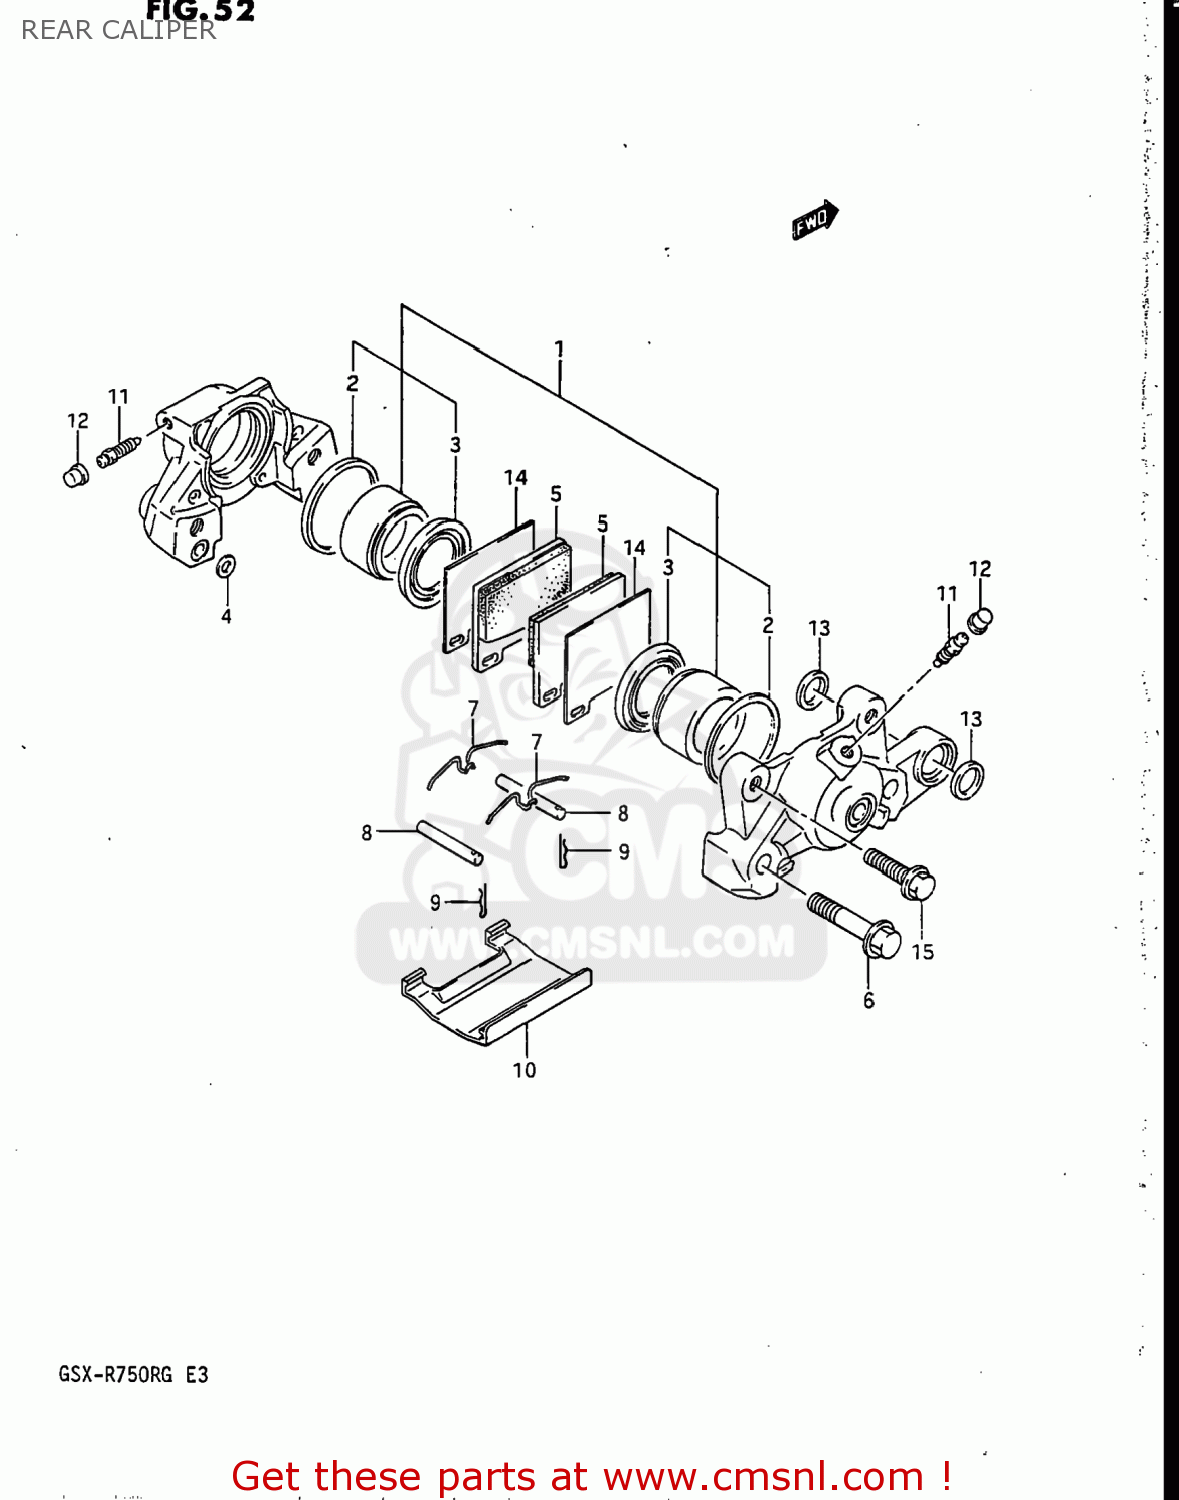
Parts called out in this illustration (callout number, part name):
1	PISTON SET
2	SEAL,PISTON
3	BOOT
4	SEAL,JOINT
5	PAD,BRAKE
6	BOLT,HOUSING
7	SPRING
8	PIN,PAD
9	CLIP,PAD PIN
10	COVER
11	BLEEDER
12	CAP,BREATHER
13	SEAL,RR CUSHION ROD LWR
14	SHIM,PAD
15	BOLT
